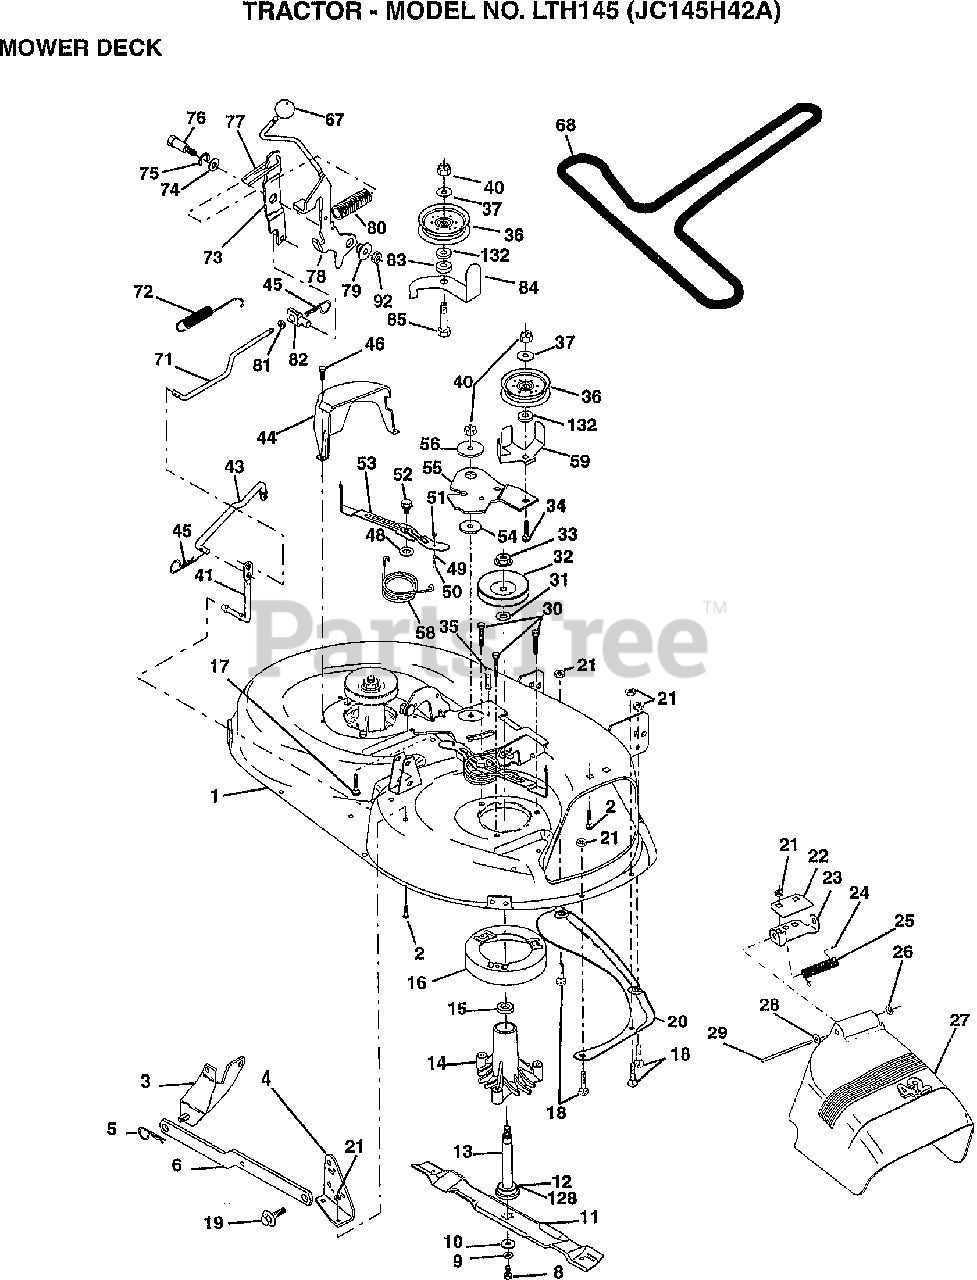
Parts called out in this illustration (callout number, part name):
2	BOLT, CARRIAGE
9	WASHER LOCK HVY 3/8
17	BOLT RDHD SQNK 3/8-16 X 2-1/4
18	BOLT RDHD SQNK 5/16-18 X 5/8
21	LOCKNUT, CROWN 5/16-18
28	WASHER 11/32 X 5/8 X 16 GA
34	BOLT RDHD 3/8-16 X 2-3/4 GR 5
37	WASHER 13/32 X 13/16 X 16 GA
38	IDLER SPRG SPACER
40	NUT, CROWNLOCK 3/8-16
85	BOLT RDHD SQ 3/8-16 X 2-1/4
92	LOCKNUT
132	WASHER 13/32 X 1-3/8 X GA
